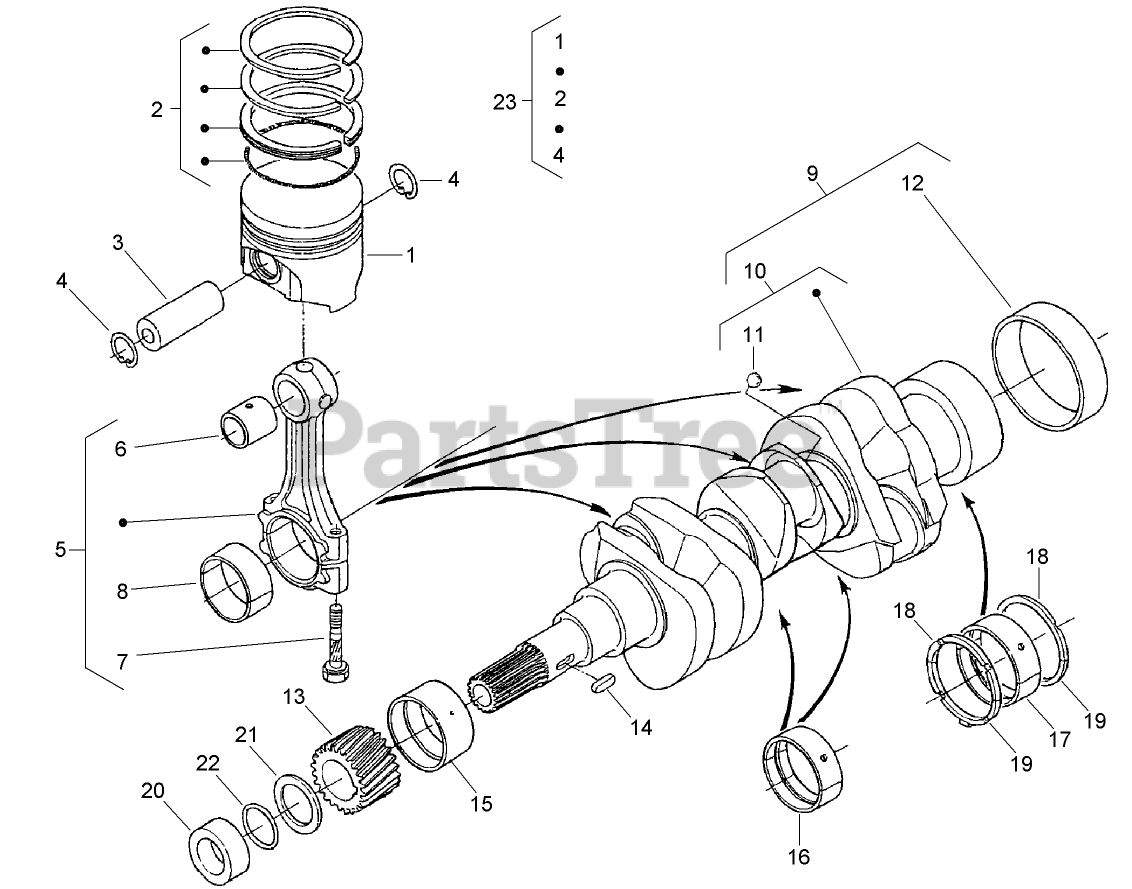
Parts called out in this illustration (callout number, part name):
1	PISTON (STD)
1	PISTON (+0.25MM)
2	PISTON RING ASM
3	PIN-PISTON
4	CIRCLIP-INTERNAL
5	CONNECTING ROD ASM
6	BUSHING-PIN, PISTON
7	BOLT-ROD, CONNECTING
8	METAL-CRANKPIN (-0.20mm)
8	METAL-CRANKPIN (-0.40mm)
8	METAL-CRANKPIN (STD)
9	CRANKSHAFT ASM
10	CRANKSHAFT
12	SLEEVE-CRANKSHAFT
13	GEAR-CRANKSHAFT
14	KEY-FEATHER
15	CRANKSHAFT-METAL (STD)
15	CRANKSHAFT-METAL (-0.2MM)
15	CRANKSHAFT-METAL (-0.4MM)
16	CRANKSHAFT-METAL (-0.2MM SET)
16	CRANKSHAFT-METAL (-0.4MM SET)
16	CRANKSHAFT-METAL (STD SET)
17	CRANKSHAFT-METAL (-0.2MM SET)
17	CRANKSHAFT-METAL (-0.4MM SET)
17	CRANKSHAFT-METAL (STD SET)
18	METAL-SIDE (STD)
18	METAL-SIDE (+0.20MM)
18	METAL-SIDE (+0.40MM)
19	METAL-SIDE (STD)
19	METAL-SIDE (+0.2MM)
19	METAL-SIDE (+0.4MM)
20	COLLAR-CRANKSHAFT
21	SLINGER-OIL
22	O-RING
23	PISTON KIT
